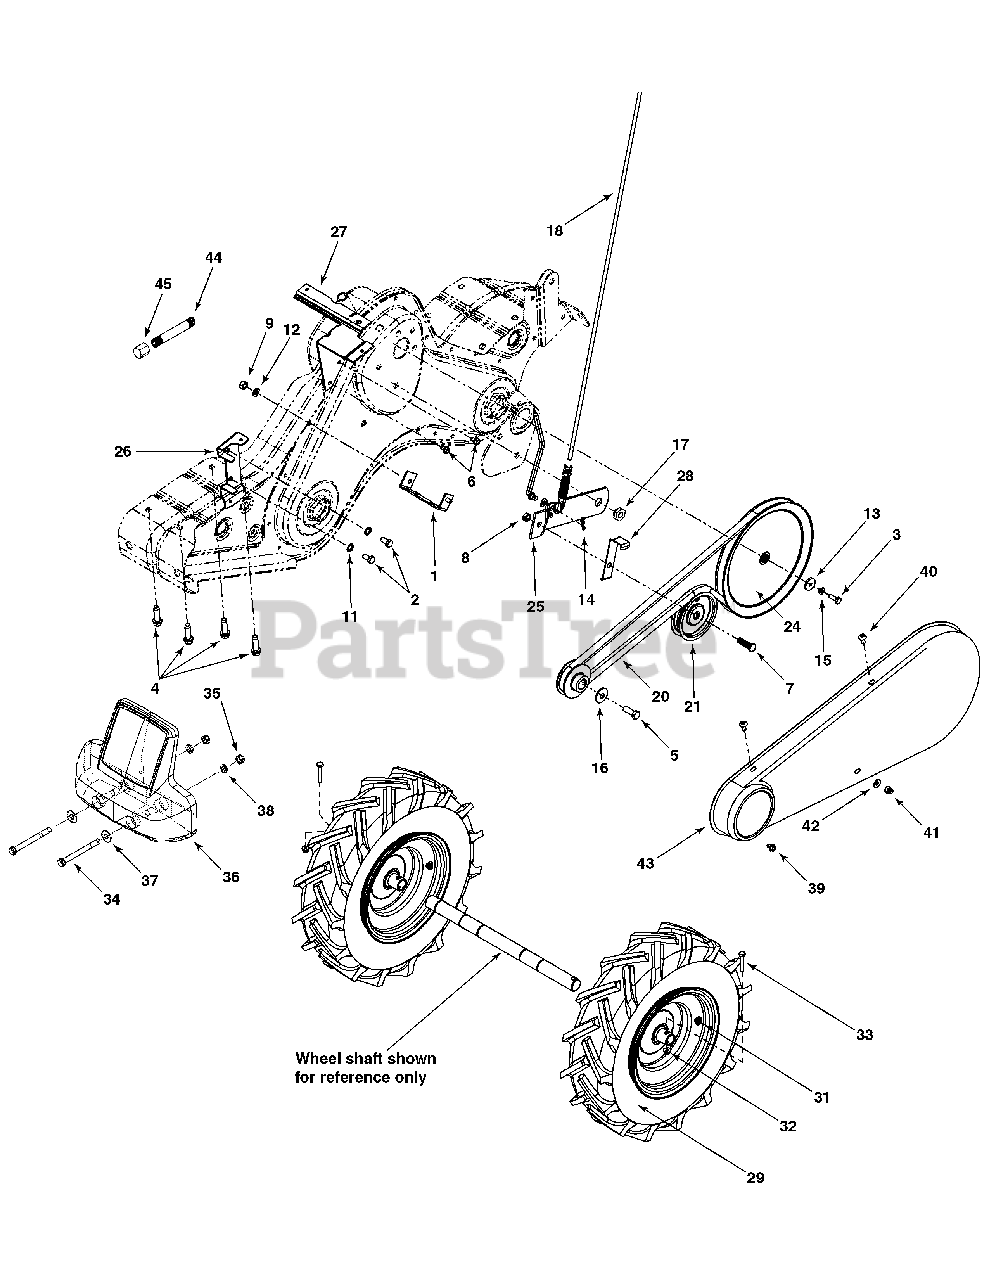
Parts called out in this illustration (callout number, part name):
1	Belt Cover Bracket Assembly
2	Hex Bolt 5/16-24 x .62"
3	Hex Bolt 1/4-28 x .75"
4	Hex Washer Screw 3/8-16 x 1.25"
5	Hex Bolt 3/8-24 x 1.0
6	Hex Washer Screw
7	Hex Cap Screw 3/8-16 x 1.25
8	Lock Jam Nut 3/8-16
9	Hex Nut 5/16-18
10	Internal Cotter Pin
11	Hairpin Clip
12	Lock Washer 5/16"
13	Flat Washer .25 ID x .93 OD
14	Spring Washer .317 ID x .625 OD
15	Lock Washer 1/4" ID
16	Bell Washer .396 ID x 1.14 OD
17	Shoulder Nut 7/16-20
18	Clutch Cable
19	Idler Pulley Rod
20	V-Belt
21	Flat Idler w/Flange 3.75 OD
22	Outer Engine Pulley Half
23	Inner Engine Pulley Half
24	Input Pulley
25	Idler Bracket
26	Belt Keeper Bracket
27	Shift Cover Bracket
28	Idler Belt Keeper
29	Wheel Assembly 16.0 x 4.6 x 8
29	Tire Only 16.2 x 4.6
31	Air Valve
32	Hex Head Screw 1/4-20
33	Flange Lock Nut 1/4-20
34	Hex Bolt 1/2-13 x 5.0
35	Hex Nut 1/2-13
36	Counterweight
37	Flat Washer
38	Lock Washer 1/2
39	Hex Screw 1/4-20 x .375
40	Screw 1/4-14 x .625
41	Lock Nut
42	Flat Washer .271 ID x .630 OD
44	Straight Pipe 1/4-3.5"
45	End Cap
